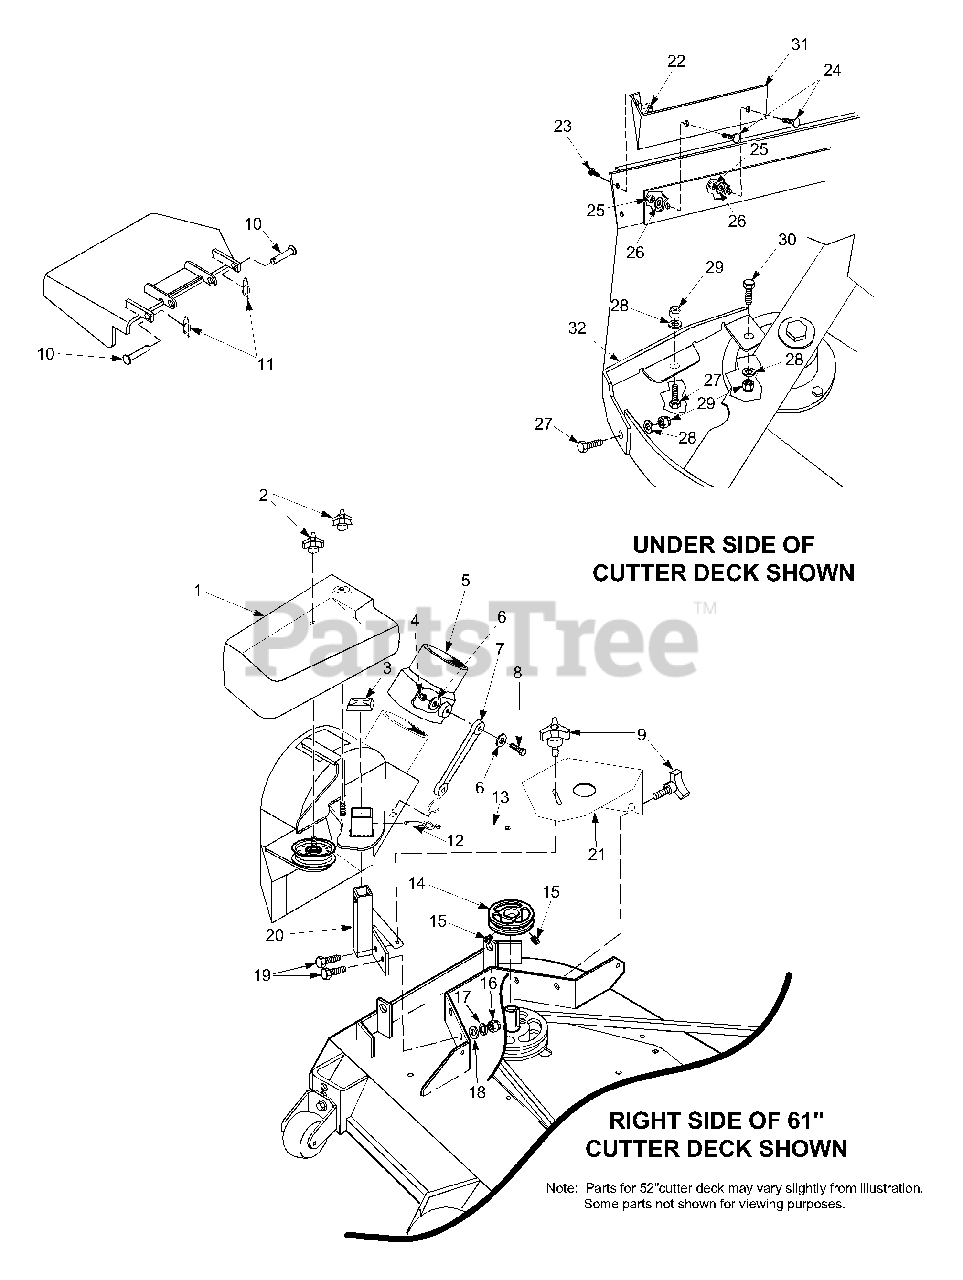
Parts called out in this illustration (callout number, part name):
1	Belt Cover, GC-STT - 52"
2	Wingnut, Plastic 3/8 Small
3	Cap, Square Vinyl
4	Nut, Elastic Stop 1/4-20
5	Adapter, Blower GC-STT
6	Flatwasher, 1/4-.312 x .750 x .065
7	Rubber Strap 7-3/4"
8	Bolt, Hex Head 1/4-20 x 1-1/4"
9	Knob W/Stud, 3/8-16 x 1-1/4"
10	Clevis Pin, 5/16 x 1-1/2"
11	Pin, Rue Cotter 5/16 Dia.
12	Pin, Ring 1/2 x 2-1/4"
13	Lanyard
14	Pulley, 4-1/2"
15	Setscrew, 5/16-18 x 3/8"
16	Nut, Elastic Stop 1/2-13
17	Lockwasher, 1/2"
18	Flatwasher, 1/2-.531 x 1.062 x .095
19	Bolt, Hex Head 1/2-13 x 1-1/2" Grade 5
20	Mounting Post Weldment, Blower - 52"
21	Belt Cover, - 52"
22	Nut, Serrated Flange 1/4-20
23	Bolt, Hex Head 1/4-20 x 3/4"
24	Bolt, Carriage 3/8-16 x 1"
25	Nut, Elastic Stop 3/8-16
26	Flatwasher, 3/8-.391 x .938 x .105
27	Bolt, Hex Head 5/16-18 x 1"
28	Flatwasher, 5/16-.375 x .875 x .083
29	Nut, Elastic Stop 5/16-18
30	Bolt, Hex Head 5/16-18 x 1-3/4"
31	Baffle, 52"
32	Baffle, 52" Deck
